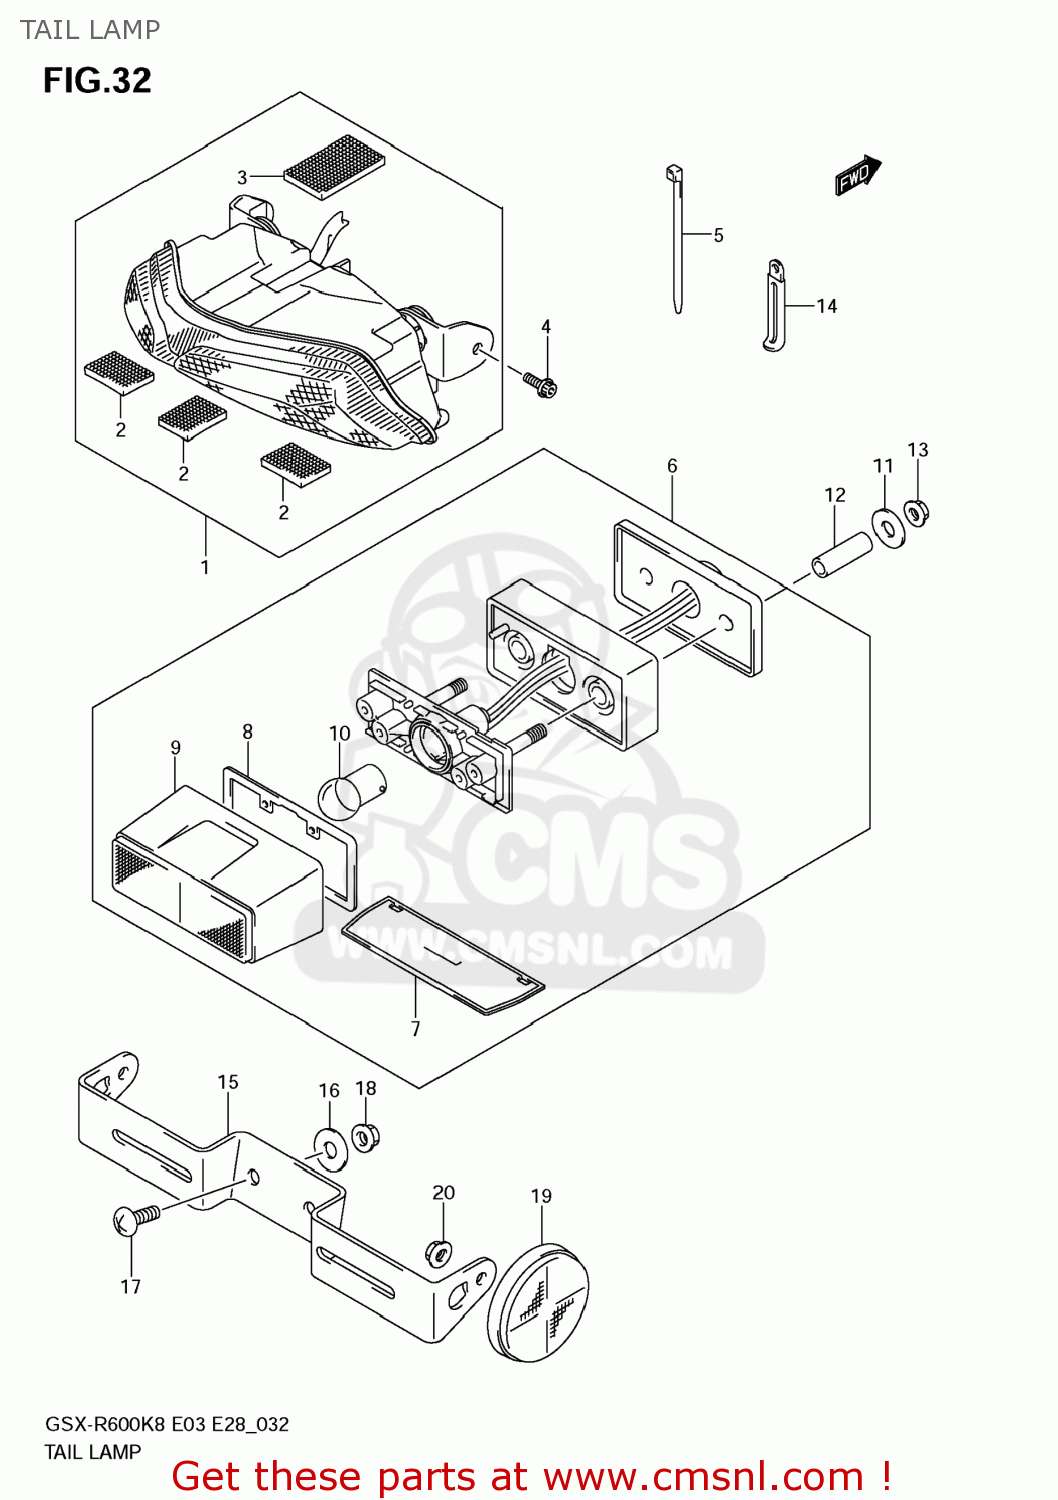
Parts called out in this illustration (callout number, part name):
1	LAMP ASSY,RR COMBINATION
2	FASTENER,FRAME COVER
3	FASTENER,RR COMB LAMP
4	BOLT(5X12)
5	CLAMP(L:145)
6	LAMP ASSY,LICE
7	LENS LICENCE
8	GASKET (NAS)
9	COVER,LICENSE LAMP
10	BULB(12V5W,BF150-40160A)
11	WASHER(6.5X20X1.2)
12	SPACER(6.5X9X33.3)
13	NUT
14	CLAMP(L:45)
15	BRACKET,LICENSE PLATE
16	WASHER(6.5X20X1.2)
17	SCREW
18	NUT
19	REFLECTOR ASSY,RR SIDE
20	NUT
